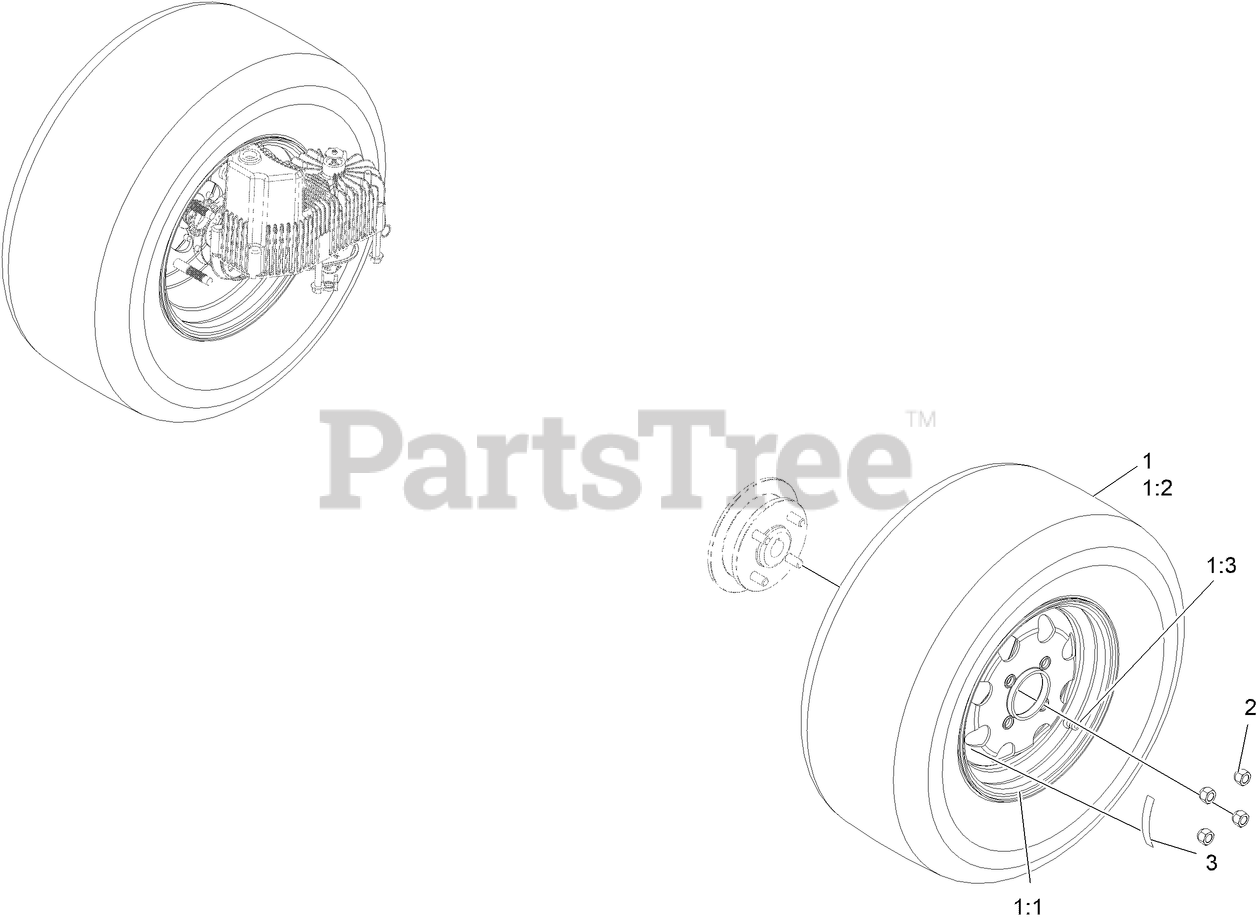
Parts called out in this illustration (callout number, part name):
1	WHEEL AND TIRE ASM
1:1	RIM ASM
1:2	TIRE, 23 X 9.50-12
1:3	Stem-Valve
2	NUT-LUG
3	DECAL-TORQUE, WHEEL HUB LUG
